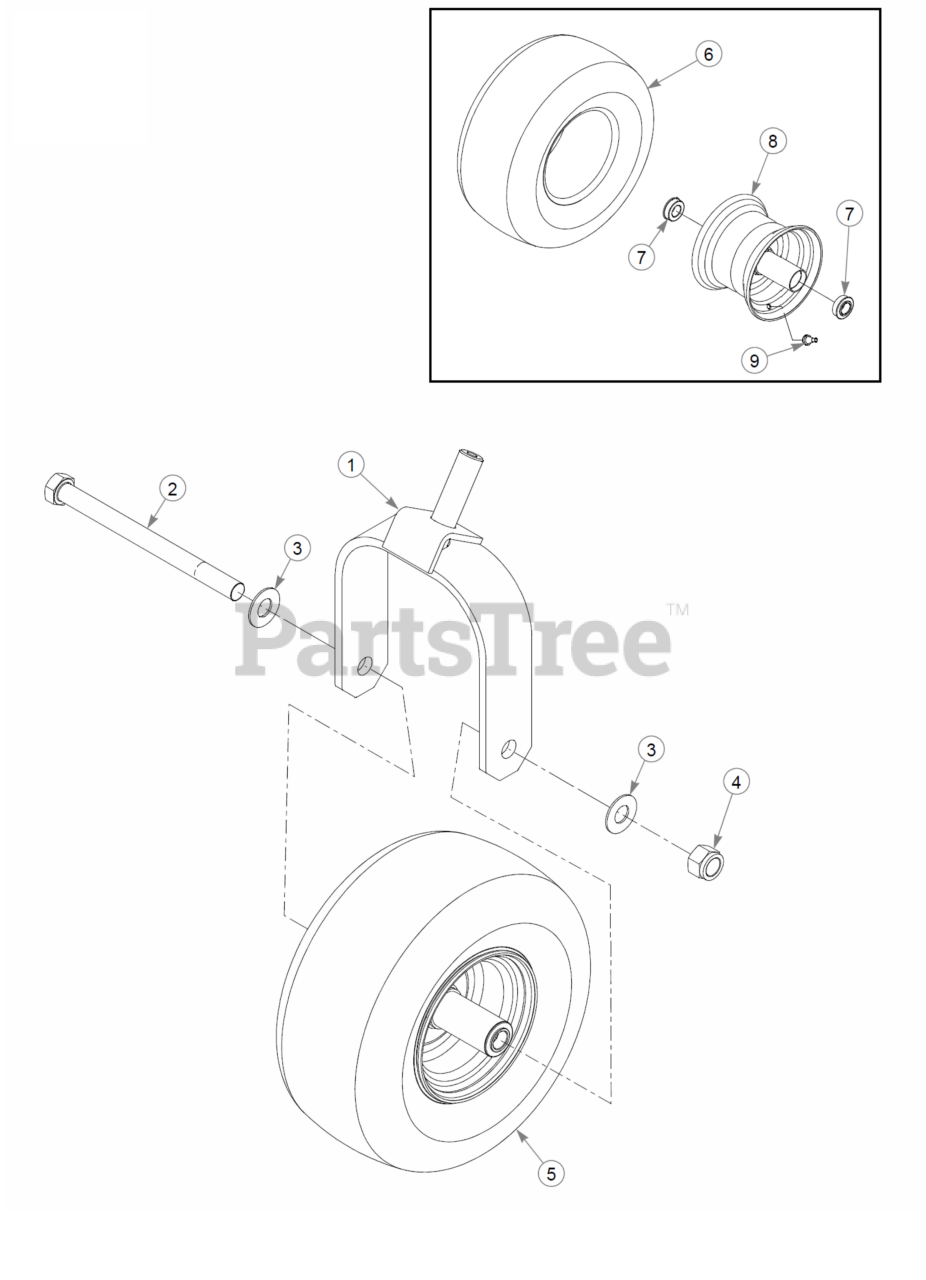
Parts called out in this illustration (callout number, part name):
1	FORK W/A
2	WHL WHEELB
3	FW .760X1.63X0.08 ZN
4	NT .750-10 HX ZN NL GR B
5	TIR/WHL 13X6.50-6 SLV
6	TIR 13X6.50-6 B4R SMTH
7	BEARING, WHEEL SEALED
8	WHL 6X4.50 SLV
9	GUARD TOE
